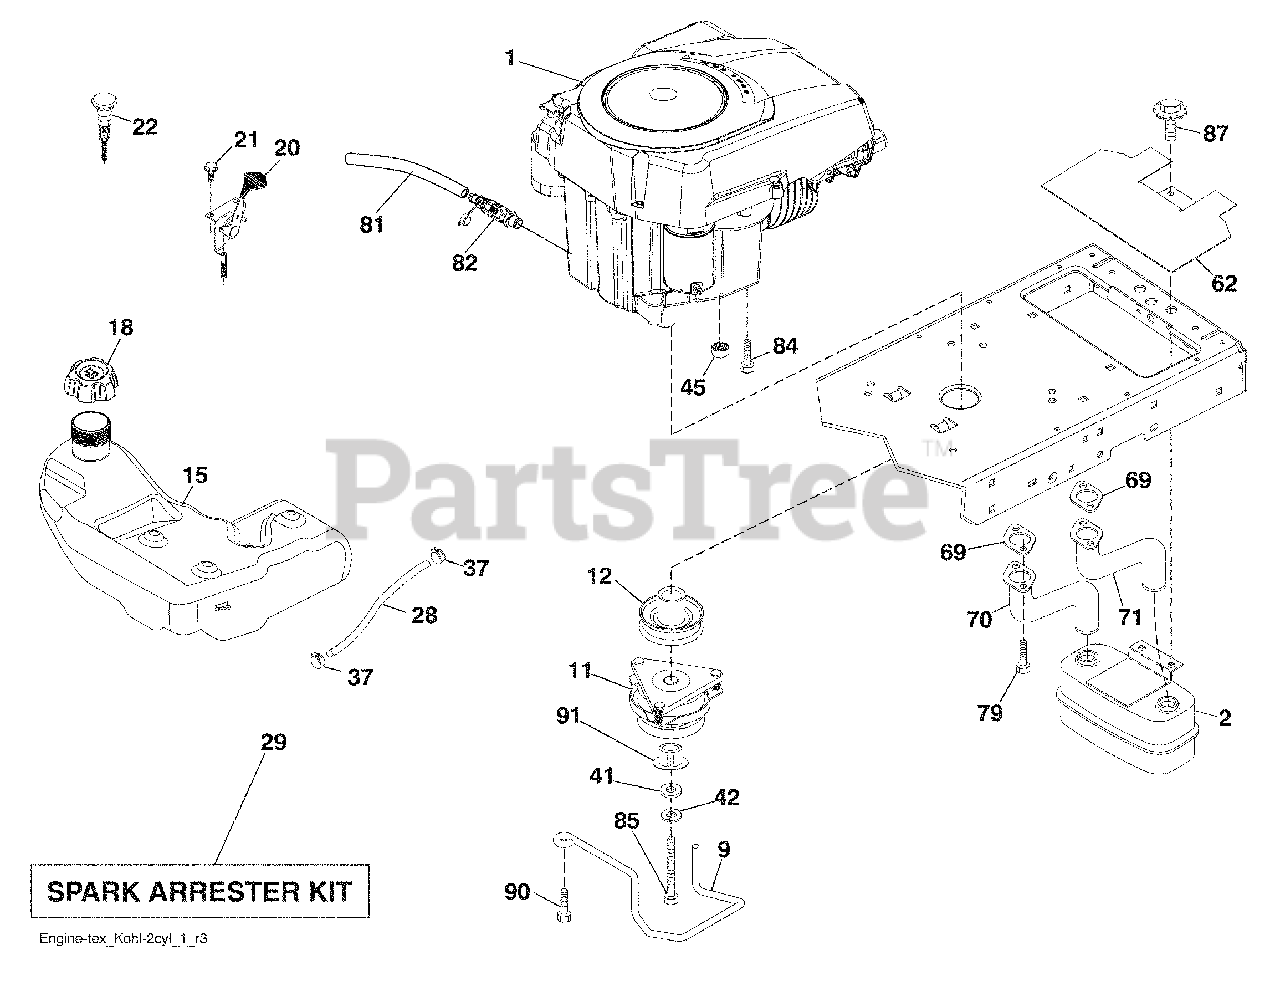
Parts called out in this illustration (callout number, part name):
9	Keeper Belt Engine
11	Clutch Electric
12	Pulley Engine
15	Tank Fuel 4.0
18	Cap Fuel
20	Control Throttle
21	Screw #10 x 0.750 BOS Thread
22	Control Choke
28	Fuel Line
29	Spark Arrester Kit
37	Clamp Hose
41	Washer 1-1/2 OD x 15/32 ID x .250
42	Washer Lock 7/16
45	Nut Keps Hex 1/4-20 unc
62	Shield Heat Muffler
70	Tube Exhaust LH
71	Tube Exhaust RH
79	Screw Socket Head 5/16-18 x .75
81	Tube Drain Oil Easy
82	Plug Drain Oil
84	Screw 3/8-16 x 1
85	Bolt Hex 7/16-20 x 3.75 Gr. 5
87	Bolt 5/16-18 unc x 1 w/Sems
90	Screw 3/8-16 x 1
